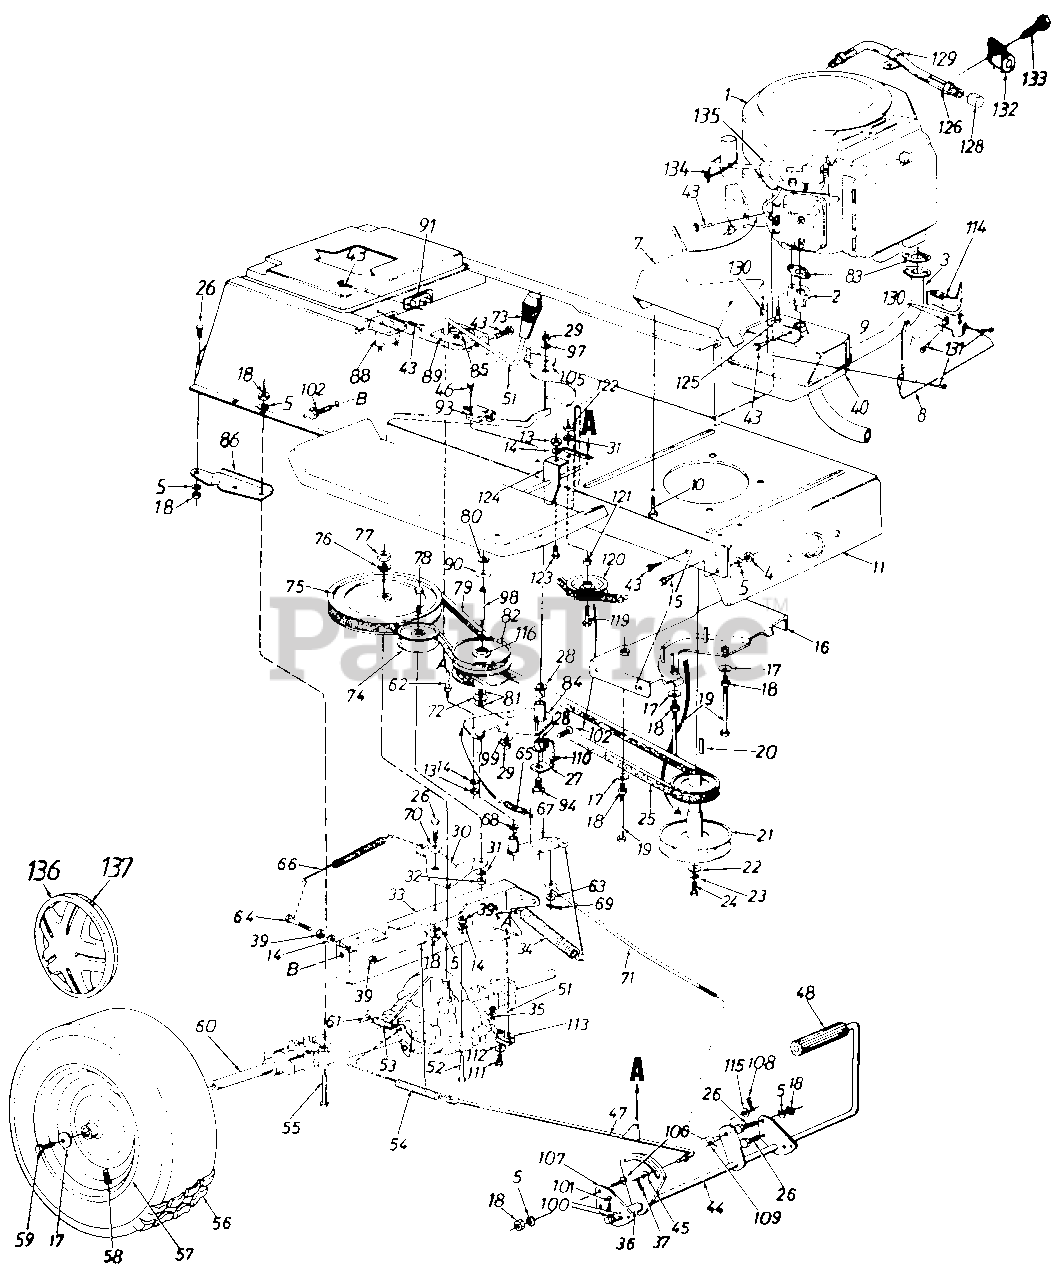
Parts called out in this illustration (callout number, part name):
1	Engine
2	Inlet Tube Ass'y.
3	Formed Tube Ass'y.
4	Hex Nut 5/16-24 Thd.
5	L-Wash. 5/16" l.D.
7	Muffler Heat Shield
8	Front Heat Shield
9	Muffler Ass'y. Comp.
10	Hex L-Wash. Tap Scr. 3/8-16 x 1.5" Lg.
11	Lower Frame Ass'y.
13	Hex Nut 1/4-20 Thd.
14	L-Wash. 1/4" I.D.
15	Rib Neck Bolt 5/16-24 x .84" Lg
16	Belt Guard Brkt. Ass y.
17	Bell-Wash. .345" I.D. x .88"
18	Hex Nut 5/16-18 Thd.
19	Hex Bolt 5/16-18 x 4.0"
20	Sq. Key 1/4" x 1/4" x 2.00"
21	Engine Pulley
22	Fl-Wash. 7/16" I.D. x 1.25"
23	L-Wash. 7/16" l.D.
24	Hex Bolt 7/16-20 x 1.50" Lg.
25	Variable-Speed Belt
26	Hex Bolt 5/16-18 x .75" Lg.
27	Bearing Shaft Bracket Ass'y.
28	Flanged Nyliner Brg. 5/8" l.D. x .88" Lg.
29	Hex Nut 3/8-24 Thd.
31	L-Wash. 818" l.D.
32	Hex Nut 3/8-24 Thd.
33	Transaxle Support Brkt.
34	Ext. Spring .94" O.D. x 7.58"
35	Inter. Cotter Pin
36	Spacer.63" I.D.
37	Cotter Pin 3/32" Dia. x .75"
39	Hex Nut 1/4-28 Thd.
40	Exhaust Muffler Sub. Ass'y.
43	Hex Wash. Hd. S-Tap Scr. l/4-20 x ,50" Lg.
44	Clutch/Brake Pedal Ass'y.
45	Fl-Wash.
46	Truss Mach. Scr. B-Tap Scr. #10 x .5" Lg.
47	Brake Rod Ass'y.
48	Foot Pad
51	Shift Lever Ass'y.
52	Hex Bolt 1/4-28 x 1.75" Lg.
53	Ext. Spring .38" O.D. x 2.5"
54	Ext. Spring .59" O.D. x 7.08"
55	Hex Bolt 5/16-18 x 2.75"
57	Wheel Rim Only
58	Air Valve
59	Hex Bolt 5/16-24 x .75" Lg.
60	Transaxle Complete
61	Brake Return Spring Anchor
62	Belt Guard Pin 1/4-20 Thd.
63	Fl-Wash. .34" I.D. x .68" O.D.
64	Hex Bolt 1/4-28 x 1.25" Lg.
65	Ext. Spring
66	Ext. Spring .62" O.D. x 6.12"
68	Flanged Bearing
69	Cotter Pin 3132" Dia.
70	Shoulder Spacer .27" Lg.
71	Speed Control Link
72	Truss Bearing .56 Dia. x 1 .25"
73	Shift Knob
74	Fl-ldler Pulley 3.25" x .75"
75	1/2n"V"-Pulley
76	L-Wash. 1/2" I.D.
77	Hex Jam Nut 1/2-20 Thd.
78	Hex Bolt 3/8-24 x 1.75" Lg.
79	Variable Speed Belt
80	Snap Ring .56" Dia.
82	Variable Speed Pulley Ass'y. 5" O.D.
83	Gasket
90	Teflon Washer .565" I.D.
91	Circuit Breaker
93	Safety Switch
94	Shld. Bolt 3/8-24 x 3.12" Lg.
97	Bell-Wash. .38" I.D. x .88"
98	Shaft .56" Dia. x 3.875" Lg.
99	Bell-Wash. 39" I.D. x 1.12"
100	Fl-Wash. .64" I.D. x .94"
101	Cotter Pin 3/32" Dia. x 1.0"
102	Hex Wash. Hd. Scr. 5/16-18 x.62" Lg.
105	Belt Guard
106	Truss Mach. Scr. 5/16-18 x .75" Lg.
107	Pedal Bracket
108	Cotter Pin 3/32" Dia. x .75"
109	Ferrule
110	Hex Bolt 5/1 6-1 8 x 10" Lg.- (Gr. 5)
111	Hex Bolt 1/4-28 x 50" Lg.
112	Bell-Wash. .265" I.D. x .75"
113	Shift Lever Link Ass'y.
114	Front Heat Shield Ext.
115	Fl-Wash. .385" I.D. x .62"
116	Needle Brgs.
119	Hex Bolt 3/8-16 x 1.25" Lg.
120	Fl-ldler w/Flanges 2.75" O.D.
121	Fl-Wash. .39" I.D. x 1.12" O.D.
122	Hex Nut 3/8-16 Thd.
123	Hex Bolt 1/4-20 x .62" Lg.
124	Spring Hanger Brkt.
125	Hex Bolt w/Washer
128	Cap Oil Drain
130	Speed Nut #10-24 Thd.
131	Hex AB-Tap Scr. #10 x .5" Lg.
133	Hex Cap Scr. M6 x 17 MM
134	Cable Tie
136	Hub Cap
137	Spring Clip
